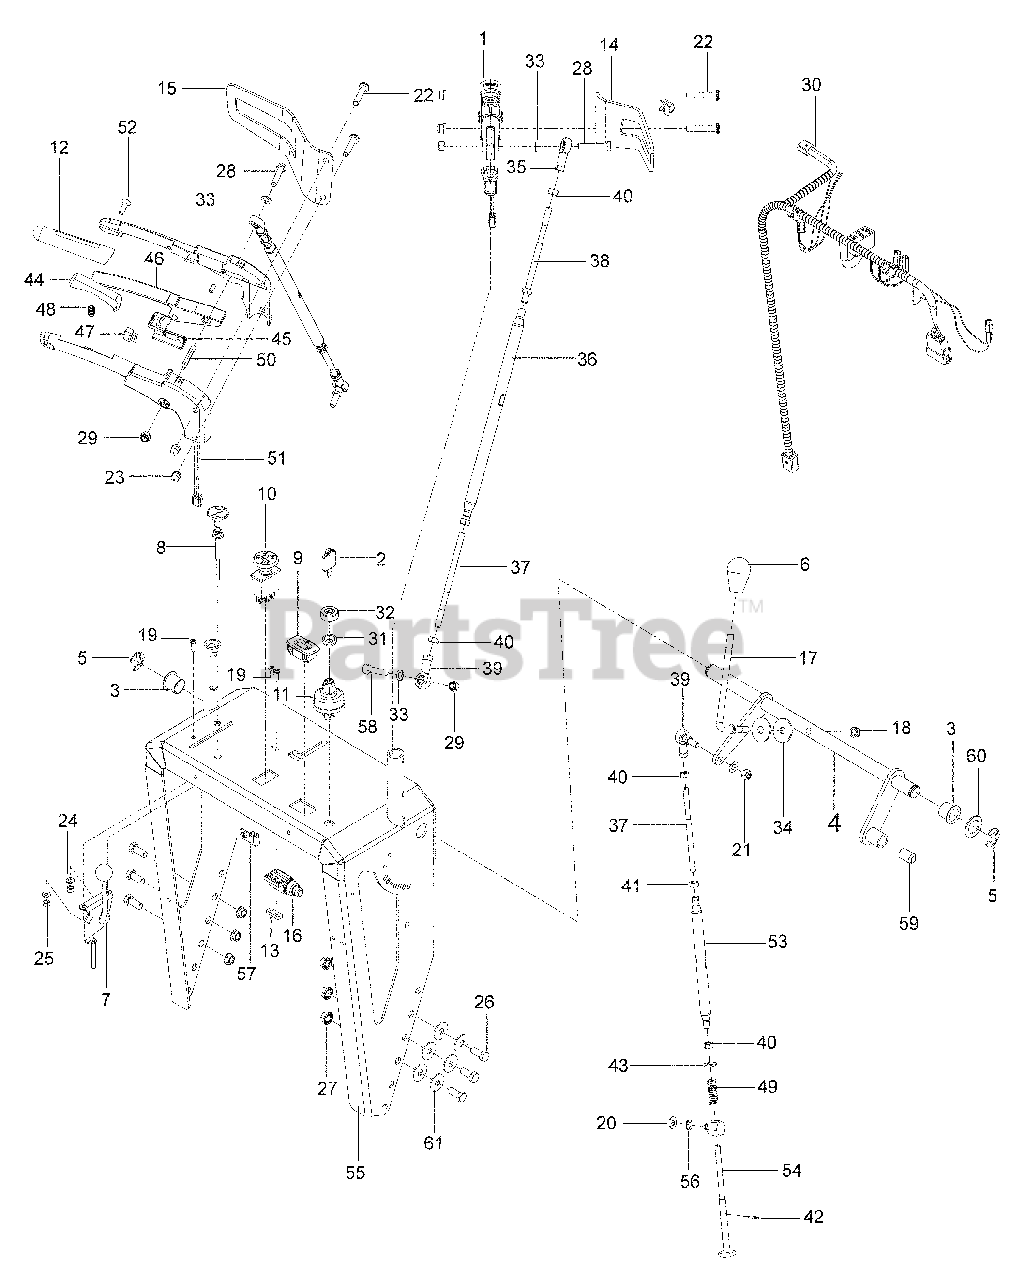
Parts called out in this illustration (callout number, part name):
1	GRIP ASSEM
3	BEARING, FLANGE
4	SPEED CONTROL
5	E RING, 20MM
6	KNOB, SHIFT
7	CONTROL, THROTTLE
8	CONTROL, CHOKE
9	METER, HOUR
10	SWITCH, CLUTCH
11	SWITCH, IGNITION
12	GRIP, FOAM
13	PLATE, NUT
14	GUARD, HAND RH
15	GUARD, HAND LH
17	ROD, SHIFT
18	NUT 3/8-16 HEX JAM NYLOC
19	SCREW #10-24 x ½ HEX
20	WASHER 3/8 SAE FLAT
21	NUT M8 x 1.25 NYLOC
22	HHFS 5/16-18 x 1¾
23	NUT, ACORN 5/16-18
24	WASHER #10 FLAT
25	NUT #10-24 HEX NYLOC
26	HCS 3/8-16 x 7/8
27	NUT 3/8-16 HEX WHIZLK NYL
28	HCS 5/16-18 x 1¾
29	NUT 5/16-18 HEX NYLOC
30	HARNESS, UPPER HANDLE
31	NUT, IGNITION SWITCH
32	CAP, IGNITION SWITCH NUT
33	WASHER 5/16 SLW
34	WASHER, CONE
35	ROD END 8 MM, RH
36	TUBE, ADJUSTING
39	ROD END 8 MM
40	NUT .8MM x 1.25 HEX
41	NUT .8MM x 1.25 LH
42	ROLL PIN 3 MM
43	WASHER, 10 MM
44	ACTUATOR, OPC
45	LOCK, NEUTRAL
50	PIN, GROOVE ¼ x 1½
51	HARNESS, SWITCH
52	SCREW, OVAL HEAD 6MM
53	TUBE, ADJUSTING
54	ROD, HEADED
55	UPPER HANDLE w/DECAL
56	E-RING, 10MM
58	HCS 5/16-18 x 1¼
61	WASHER, SPRING
